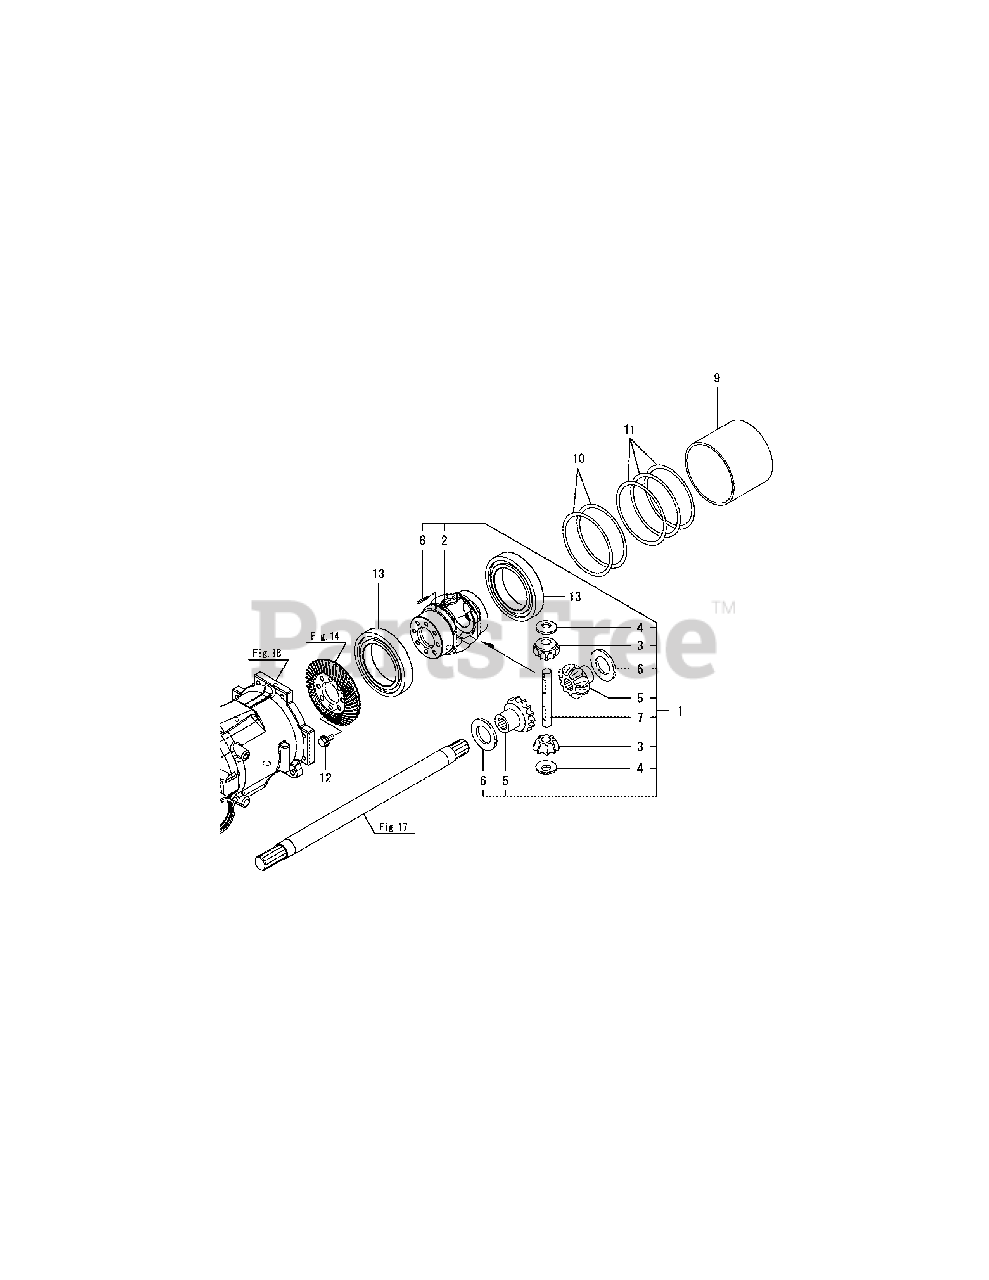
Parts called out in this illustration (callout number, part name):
1	HOUSING ASSY, DIFF.
2	HOUSING,DIFFERENTIAL
3	PINION, DIFFERENTIAL
4	LINER, DIFFERENTAIL
5	GEAR, DIFF. SIDE
7	SHAFT, DIFF. PINION
8	SPRING PIN 6X40
9	COLLAR, DIFFERENTIAL
12	BOLT M 8X 20 PLATED
